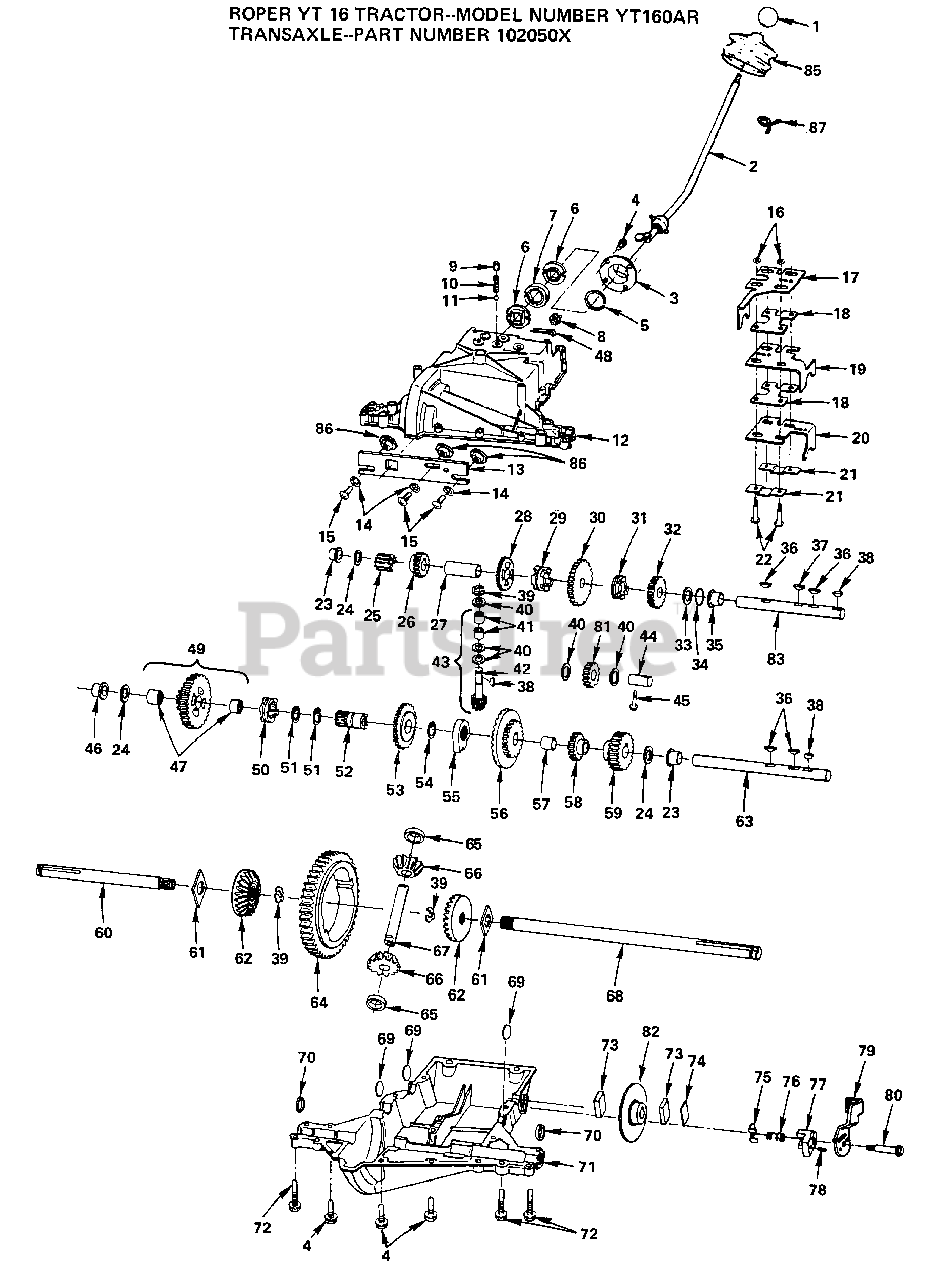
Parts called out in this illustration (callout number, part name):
4	SCREW HEX CRT
5	SPRING - WAVE
6	SOCKET - LEVER, SHIFT
7	INSERT-SHIFT YT
15	SCREW.HXHD.10-2
17	FORK - SHIFT, PRIMARY
18	PLT-SEPARATOR L
20	FORK-SHIFT YTV
25	GEAR-SPUR 13T Y
28	GEAR - SPUR, 27T
30	GEAR - SPUR, 37T
39	KLIP RING
40	"T, BEARING"
44	SHAFT - IDLER, REVERSE
45	SCREW YTV
49	GEAR ASSY YTV
63	SHAFT PRIMARY Y
72	SCREW YTV
73	PAD-BRAKE YTV
74	SHIM - BRAKE, HARDENED
75	PLATE, BEARING
77	CALIPER - BRAKE
80	BOLT - SHOULDER
82	DISC-BRAKE YTV
84	LUBRICANT YTV
